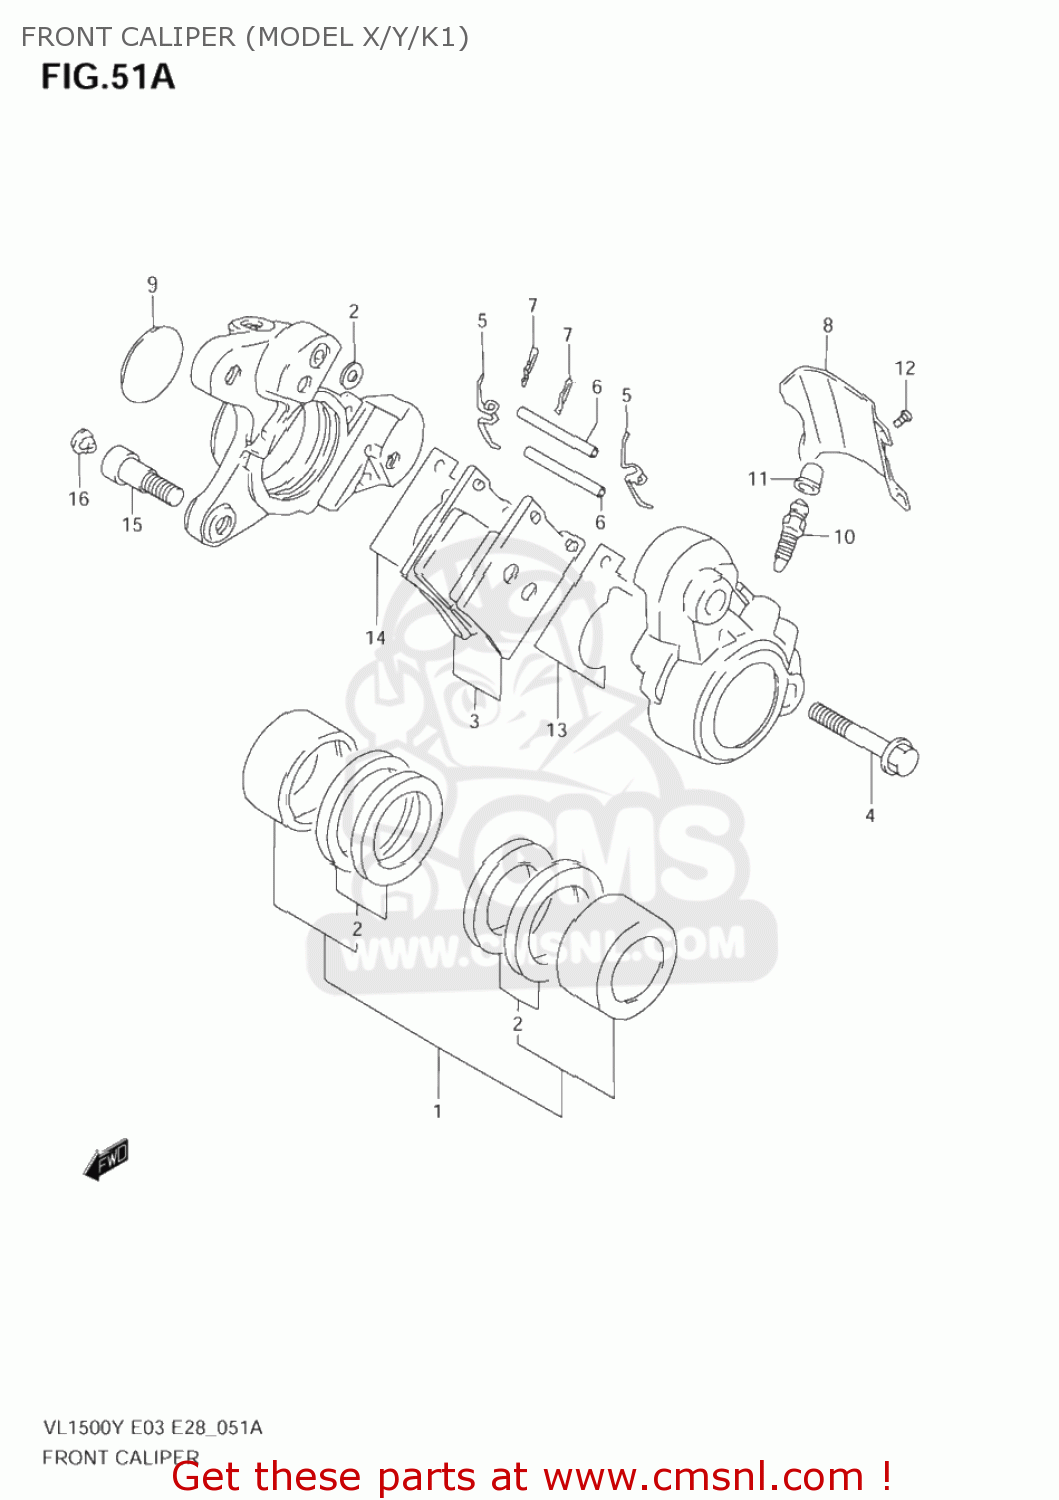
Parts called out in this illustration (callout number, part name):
1	PISTON SET
2	SEAL SET,PISTON
3	PAD SET (NAS)
4	BOLT,HOUSING
5	SPRING
6	PIN,PAD
7	CLIP,PAD PIN
8	COVER,CALIPER HOUSING,DUST
9	CAP,CALIPER
10	BLEEDER
11	CAP,BLEEDER PLUG
12	SCREW,CALIPER COVER(4X6)
13	SHIM,INNER
14	SHIM,OUTER
15	BOLT(10X33)
16	CAP(OD:12)
